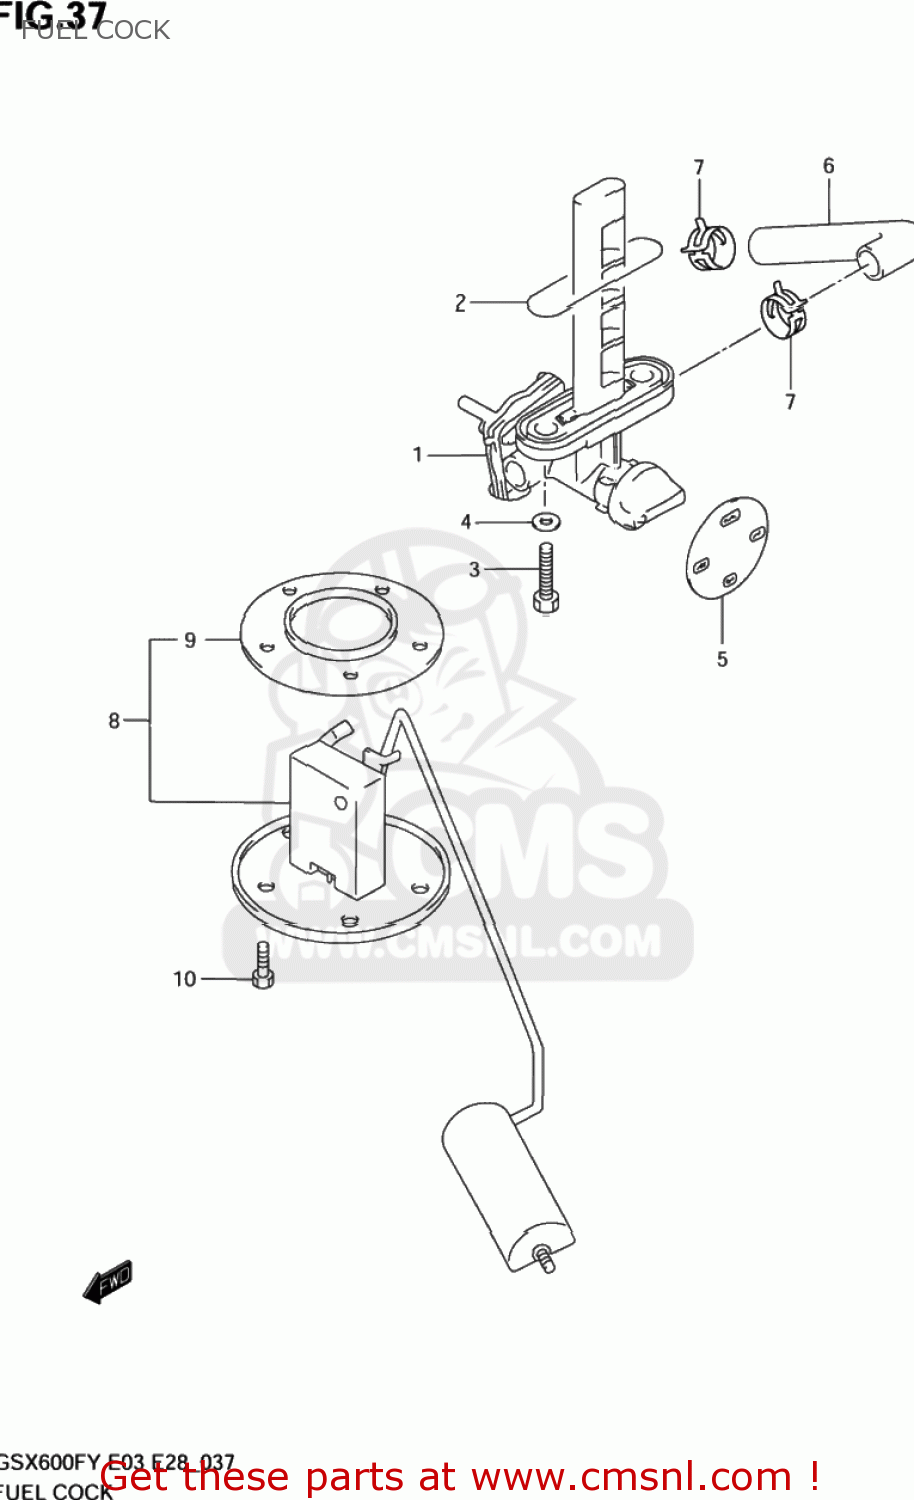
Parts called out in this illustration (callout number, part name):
1	COCK ASSEMBLY,FUEL
2	O RING
3	BOLT(6X20)
4	GASKET(6.4X11.5X0.8) (NAS)
5	LABEL,FUEL COCK(GRAY)
6	HOSE,FUEL ON
7	CLIP
8	GAUGE ASSY,FUEL LEVEL SENDER
9	GASKET,FUEL LEVEL GAUGE (NAS)
10	BOLT 5X10
